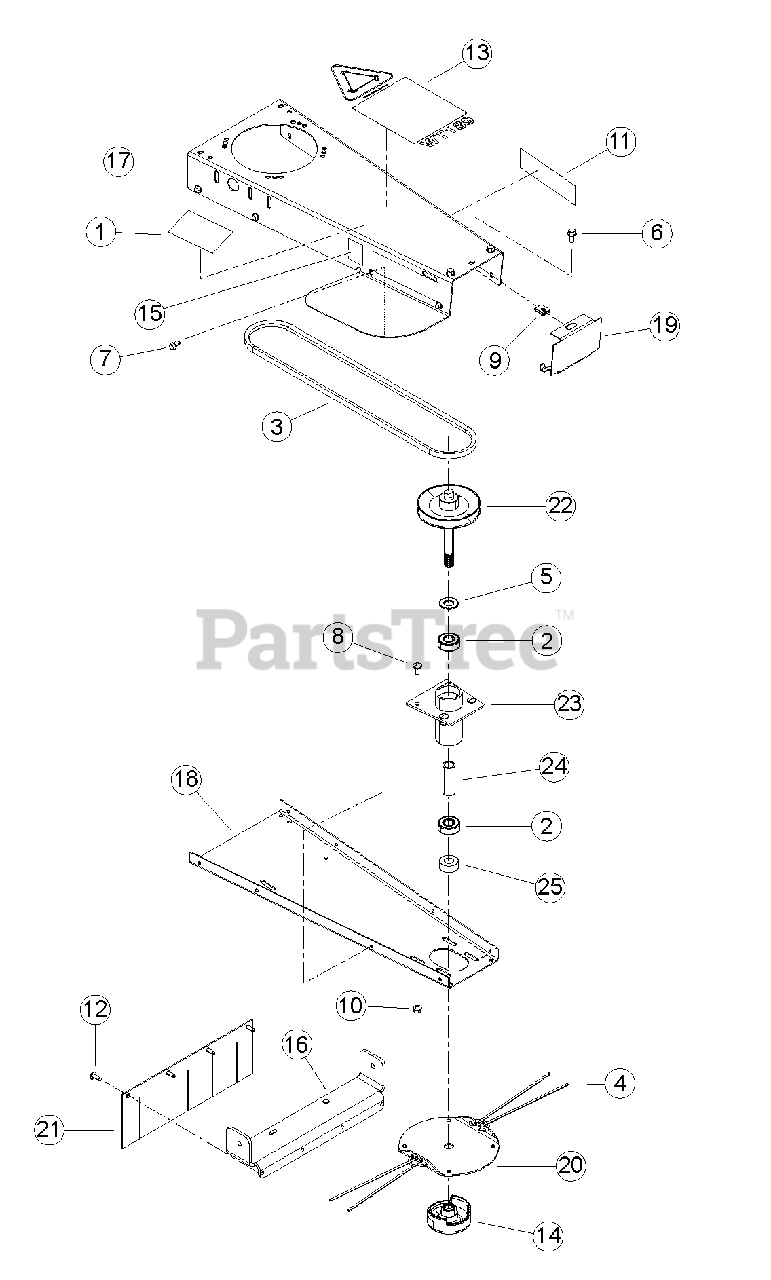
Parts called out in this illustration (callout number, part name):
1	DECAL, GRINDER DANGER
2	BEARING, 3/4 BALL
3	BELT, 4L 53 ARAMID
4	STRING, .155 X 20-1/2
5	WASHER,3/4"SAE FLAT ZP,21PC/LB
6	BOLT, 5/16 X 3/4 FLANGE NC
7	SCW,11/32*7/8 HWH AB THREAD ZP
8	BOLT, 5/16 X 3/4 GR5 NC ZP CRG
9	NUT 5/16"-18 TINNERMAN U-TYPE
10	NUT, 5/16-18 NYLOCK-FLANGE
11	DECAL, ECHO BEARCAT 6.82 X 1.90
12	RIVET, PLASTIC 1/4 X 7/8
13	DECAL, WT189 INFORMATION
14	MOWBALL, CAST TRIMMER
15	DECAL, ECHO BEARCAT QR CODE
16	PLATE, TRIMMER AXLE
17	BODY, TRIMMER STANDOFF
18	BOTTOM, TRIMMER STANDOFF
19	COVER, TRIMMER STANDOFF
20	DISK, TRIMMER HEAD
21	FLAP, TRIMMER
22	WELDMENT, TRIMMER PULLEY
23	WELDMENT, SPINDLE HUB
24	SPACER, TRIMMER SPINDLE
25	SPACER, TRIMMER HEAD
